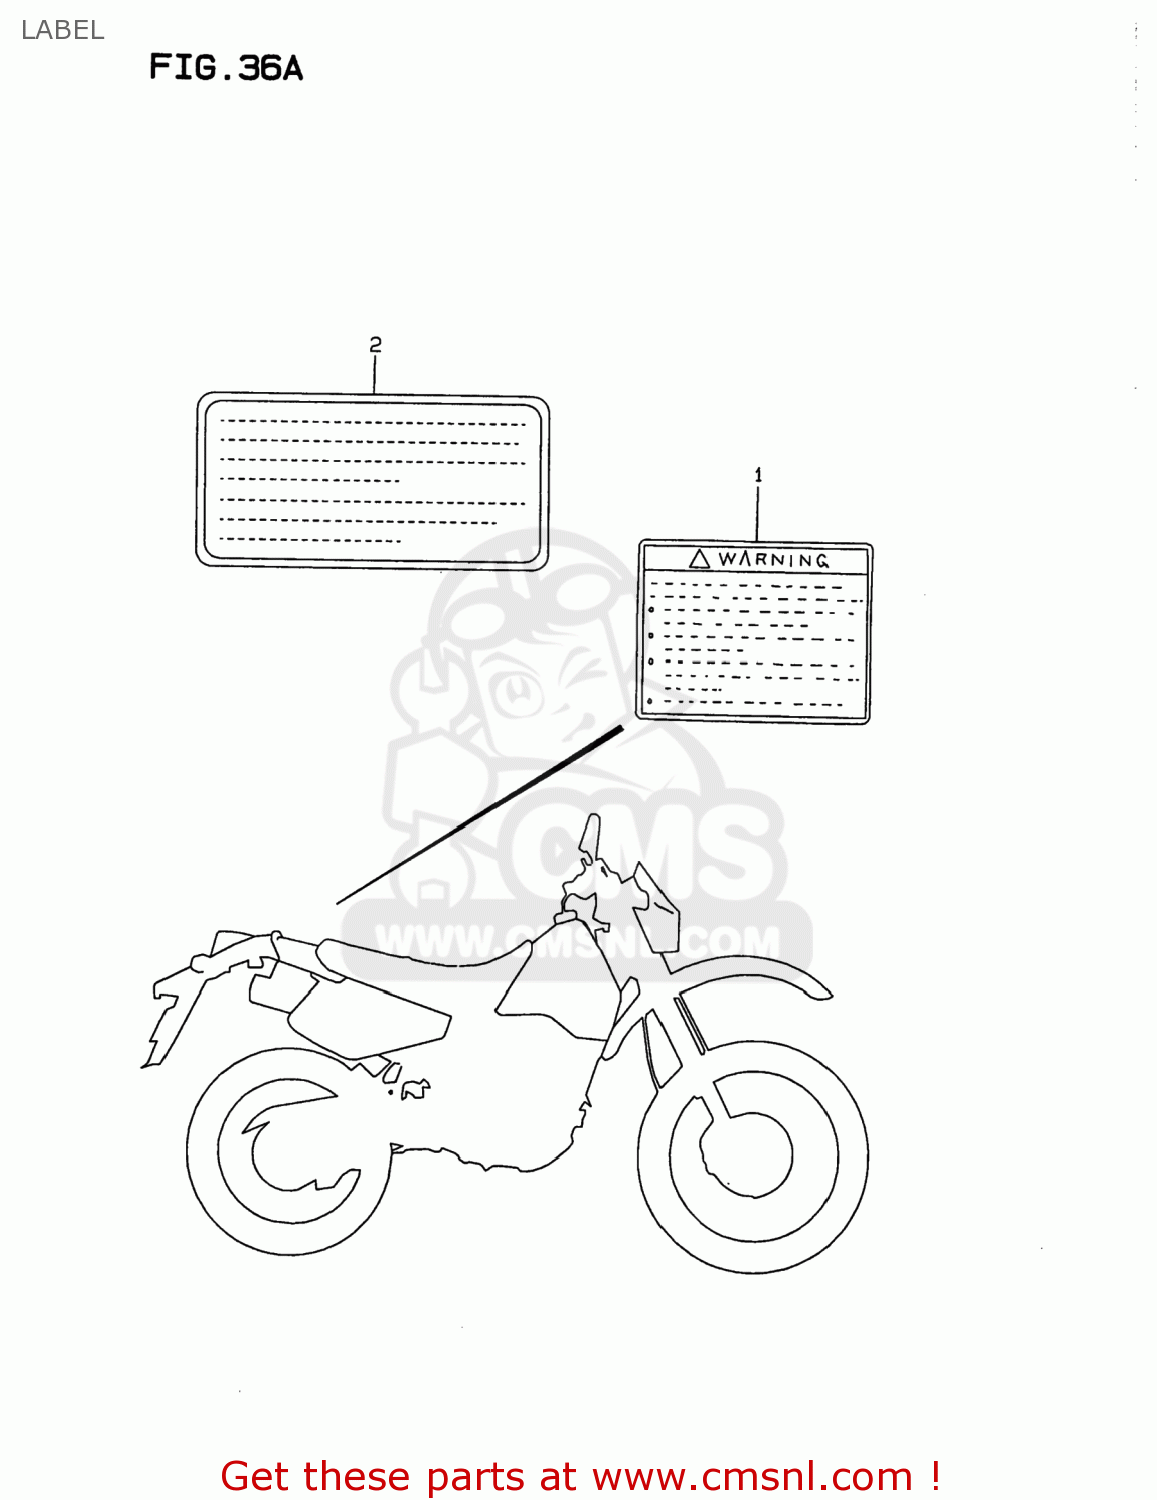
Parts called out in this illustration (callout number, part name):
1	LABEL,WARNING SAFETY
2	LABEL (MANUAL NOTICE)
3	MANUAL, OWNER'S
